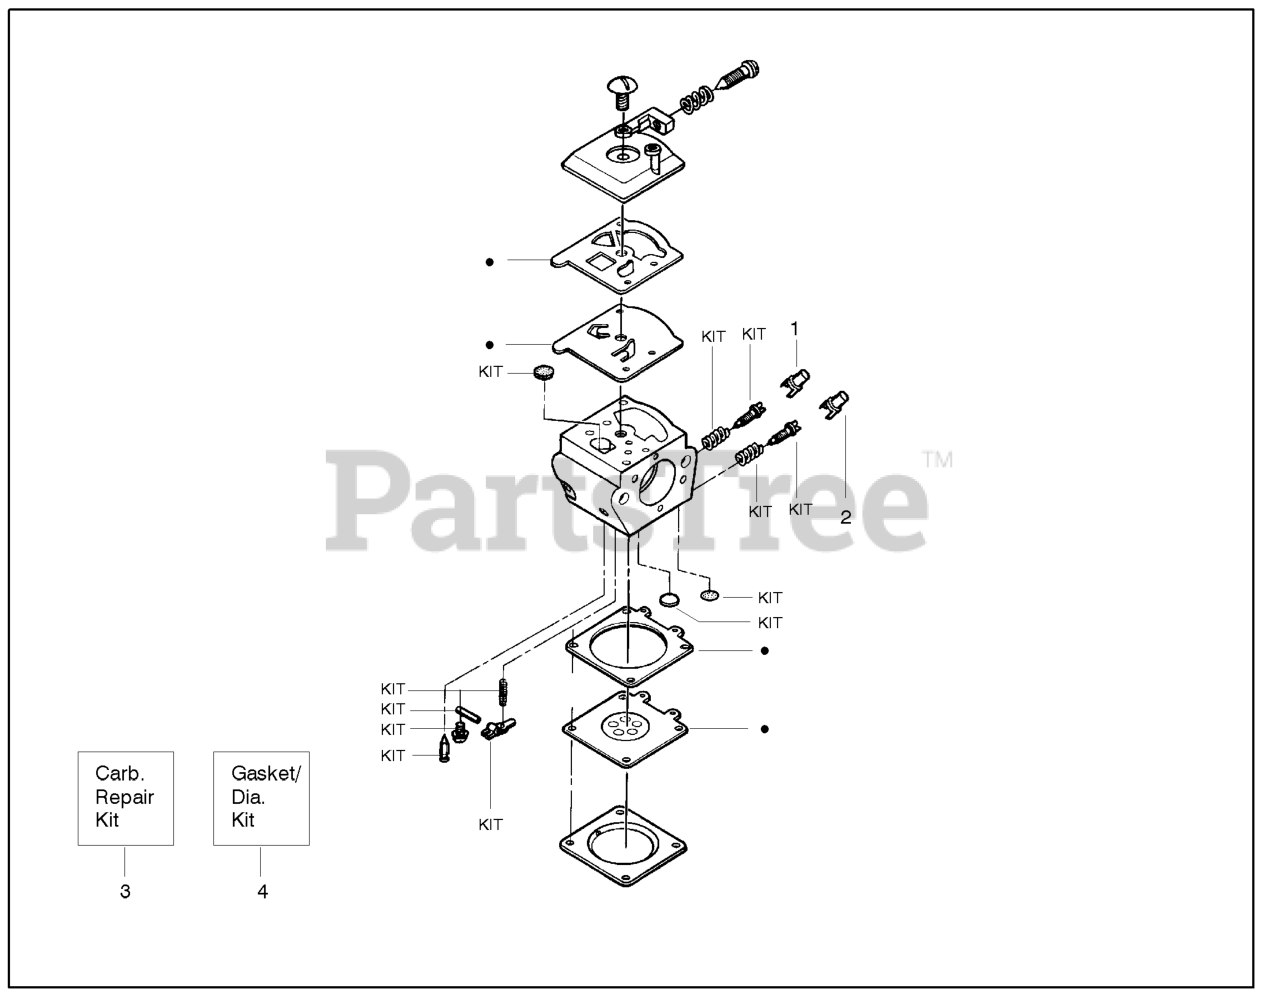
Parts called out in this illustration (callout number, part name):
1	LIMITER CAP-HIGH
2	LIMITER CAP-LOW
3	CARB REPAIR KIT
4	GASKET/DIAPHRAGM KIT
